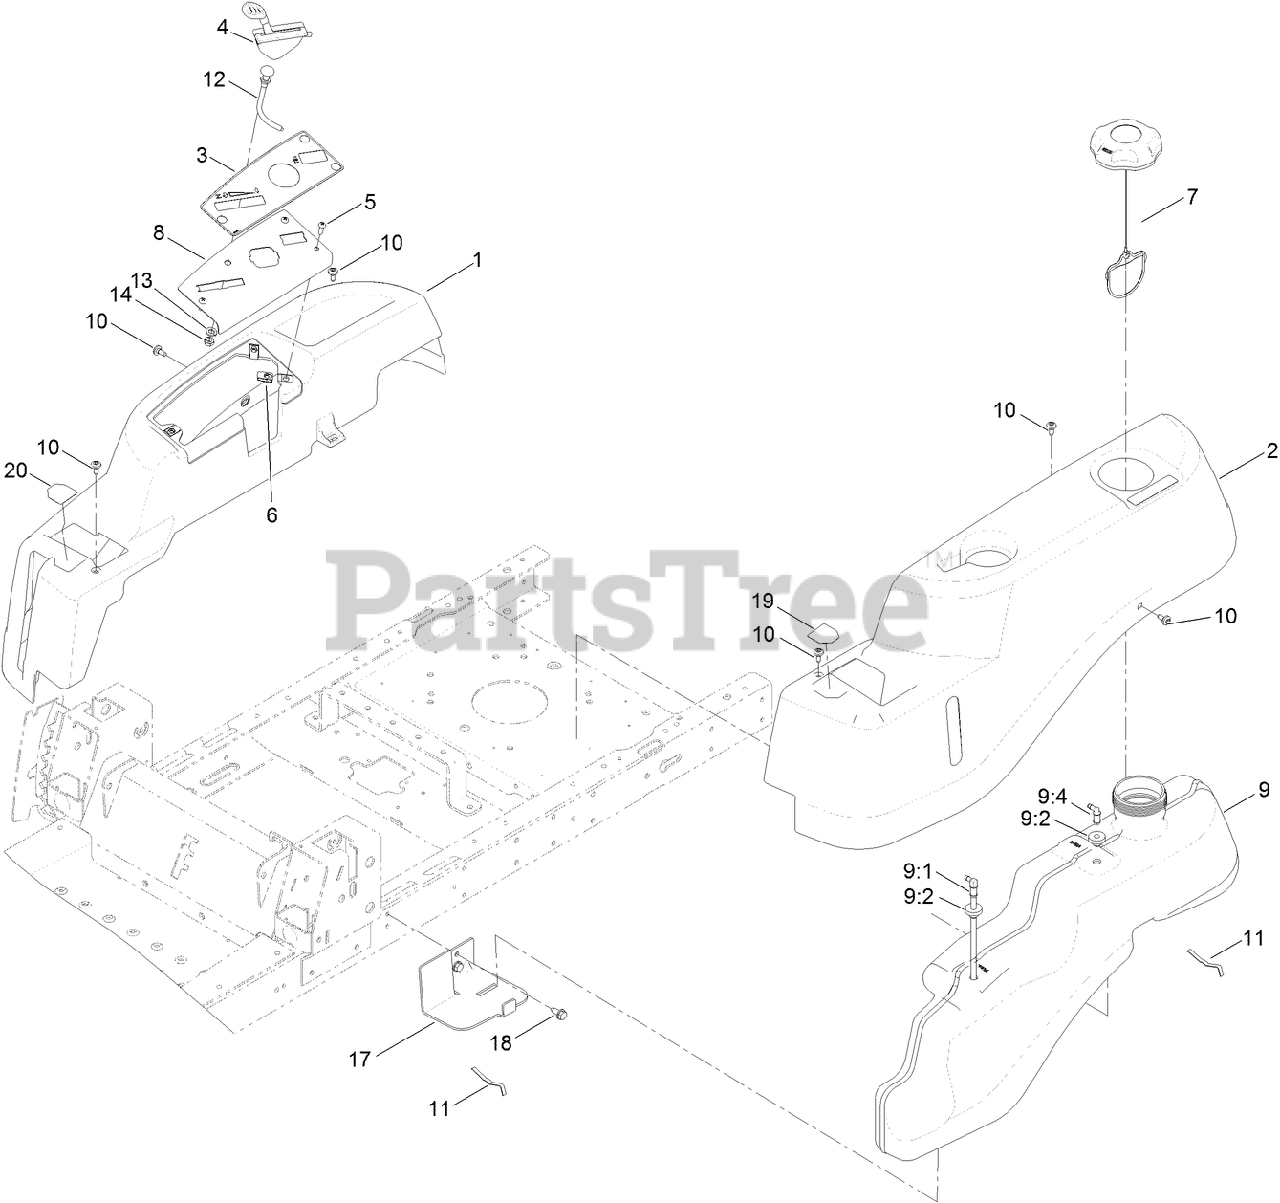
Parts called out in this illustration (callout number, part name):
1	POD-RH
3	DECAL-PANEL, CONTROL
4	CABLE-THROTTLE
5	SCREW-PRH
8	PLATE-CONTROL
9	FUEL TANK ASM
9:1	CONNECTOR-ELBOW, 90 DEG
9:2	BUSHING
9:4	FITTING-PLASTIC
10	SCREW-SHOULDER
11	SPRING
12	CABLE-CHOKE
13	WASHER-LOCK
14	NUT-HJ
17	SUPPORT-TANK, FRONT
18	SCREW-HWHTF
19	DECAL-LEVER, CONTROL (LH)
20	DECAL-LEVER, CONTROL (RH)
